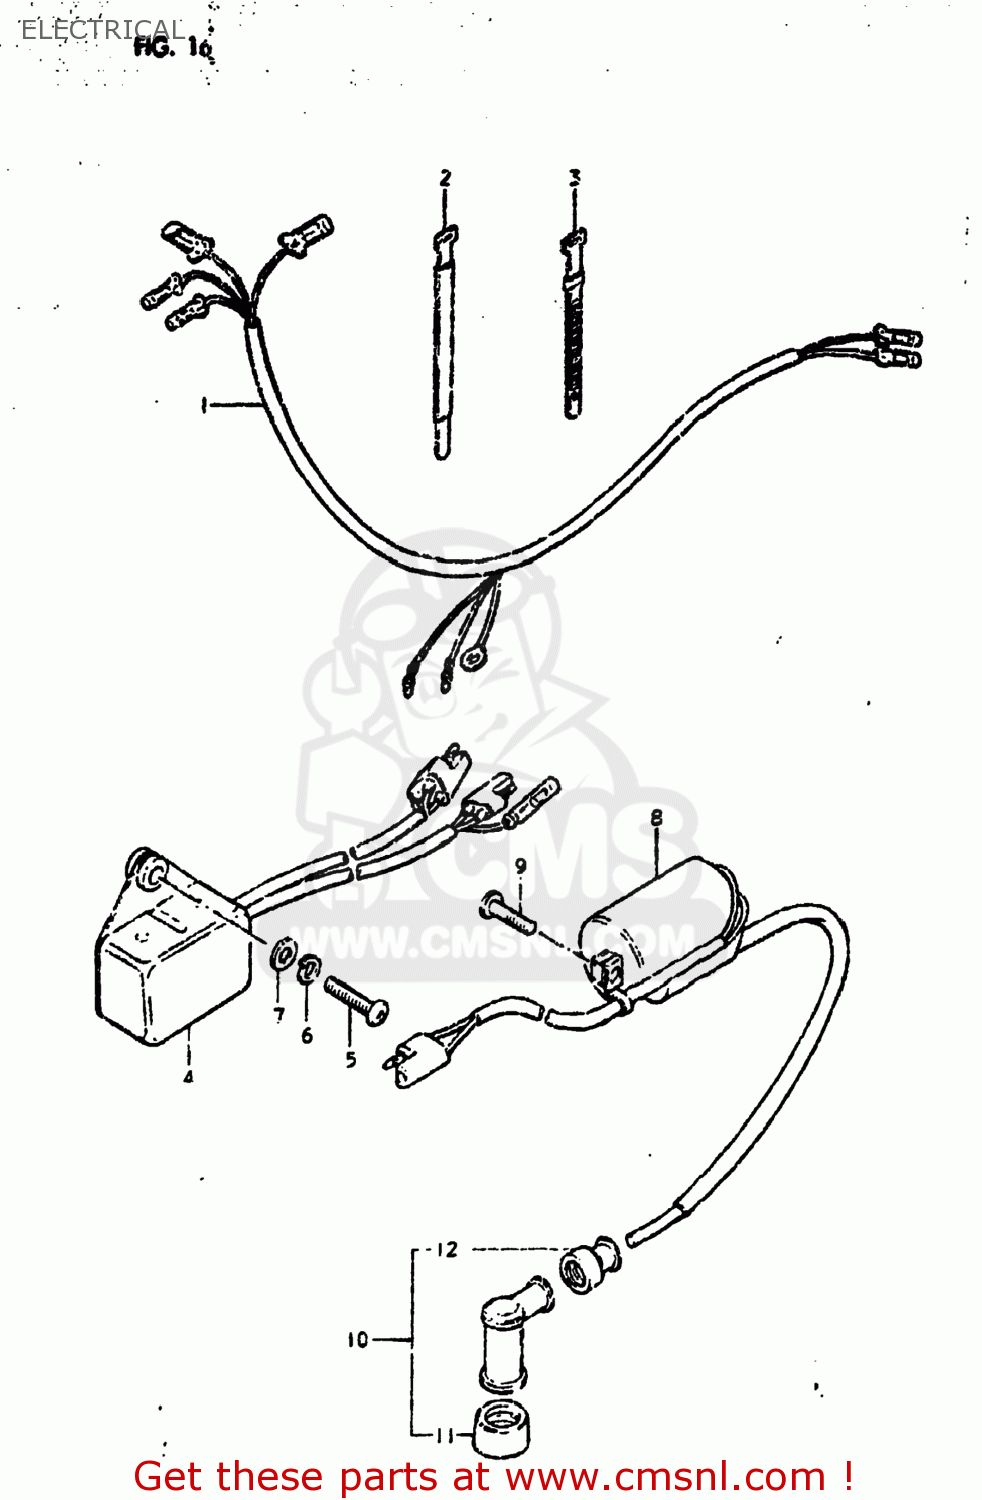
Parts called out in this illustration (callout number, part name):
1	HARNESS,WIRING
2	CLAMP
3	CLAMP(L:120)
4	CDI UNIT
5	SCREW
6	LOCK WASHER
7	WASHER
8	COIL ASSEMBLY,IGNITION
9	SCREW 5X20
10	CAP,SPARK PLUG
11	SEAL,SPARK PLUG
12	SEAL,SPARK PLU
